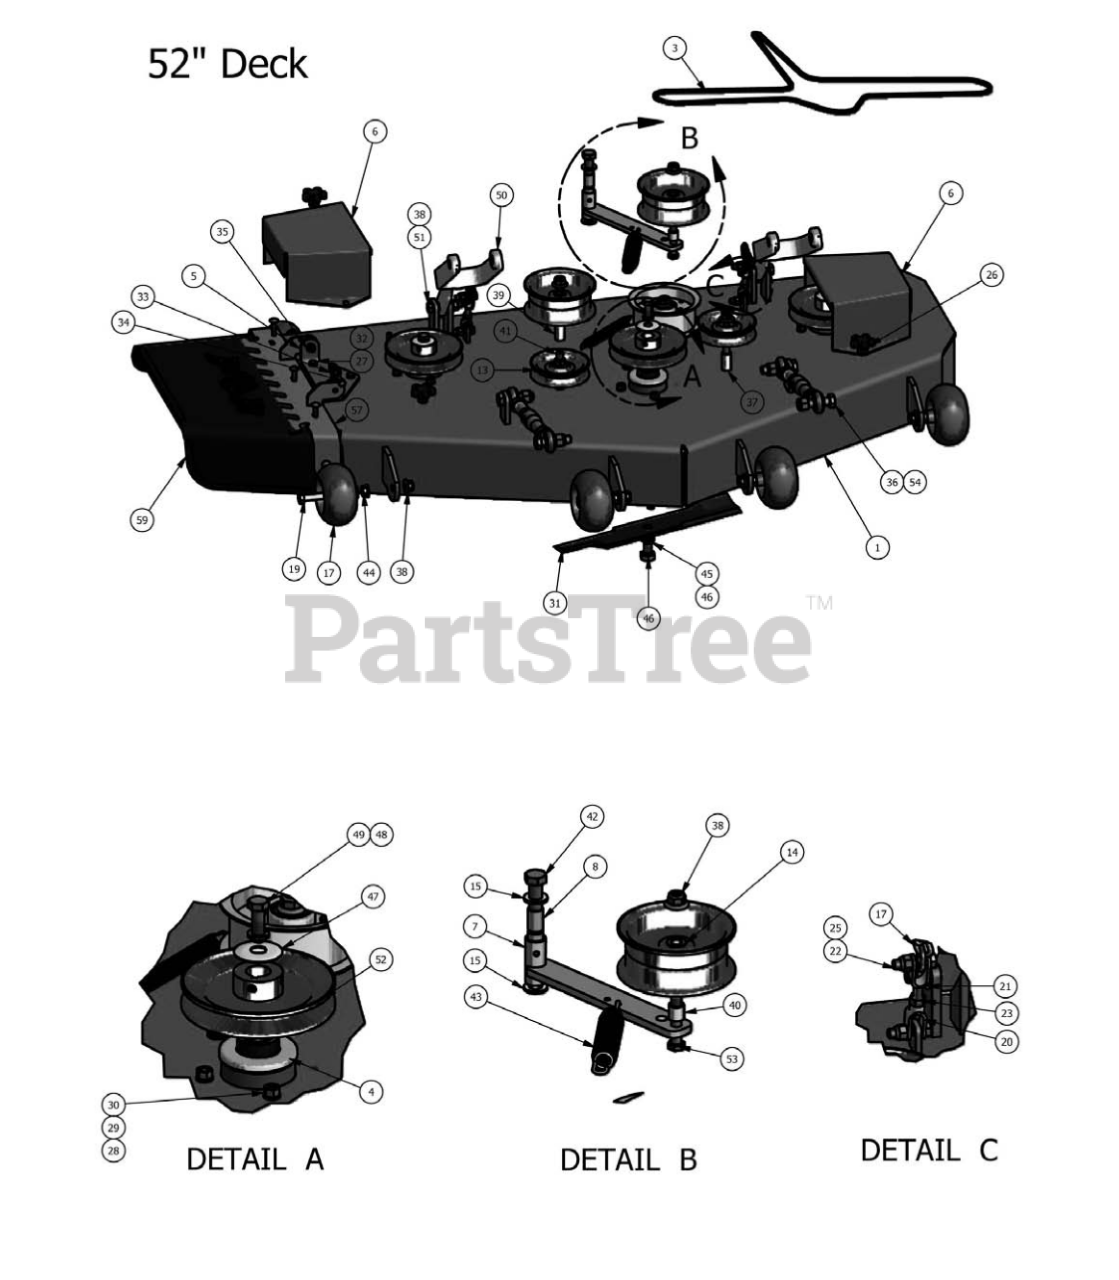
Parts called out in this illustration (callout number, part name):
1	52" Deck Shell
2	52" Deck Assembly
3	52" Deck Belt
4	Double Bearing Spindle (Complete)
5	Discharge Chute Hanger
6	Pulley Cover
7	Deck Idler
8	5/8" ID x 1 1/8" Brass Bushing
9	1/2" x 3" Hex Bolt
10	1" Collar Spacer
11	1/2-13 Nylon Flange Nut-Orange
12	deck Idler Spring
13	43/4" Idler Pulley
14	5 3/4" Deck Idler Pulley
15	.635 ID Plastic Washer
16	Turnbuckle (Top Link)
17	Anti-Scalp Rollers
18	Deck Wheel Assembly
19	1/2" x 4" Bolt (Grade 8)
20	Female Yoke
22	3/8" x 1 1/2" Hex Bolt
23	3/8" Hex Nut
24	3" Chain Assembly
25	3/8 Nylock Nut
26	5/16" Knob
27	3/8" x 3/4" Hex Bolt
28	3/8 x 1 1/4 Bolt
29	3/8" Lock Washer
30	3/8" Hex Nut
31	52" Fusion Blade
32	3/8" Flange Nut
33	.360 ID Plastic Washer
34	5/16" x 1" Hex Bolt
35	5/8 Nylock Nut
36	5/8" x 2 1/2" Hex Bolt
37	Pup Pulley Spacer
38	1/2-13 Nylon Flange Nut-Orange
39	13/4" Pulley Spacer
40	3/4 OD x 1/2 ID x 3/4 Length
41	1/2 x 3 1/2 Flange Bolt
42	5/8" x 4" Hex Bolt
43	Deck Idler Spring
44	1/2" Flange Nut
45	5/8" Lock Washer
46	5/8 x 1 1/2" Grade 8 Bolt
47	Cup Washer
48	1/2" Lock Washer
49	1/2" x 1 1/2" Fine Thread Bolt
50	Deck Arm Assembly
51	1/2" x 2 1/2" Hex Bolt
52	5" Deck Pulley
53	1/2 x 3" Bolt
54	5/8 Std NC Nylock Nut
55	52" Lower Hanger
56	5/16" Nylock Flange Nut
57	52" Discharge Chute Upper Hanger Plate
58	5/16" x 1 1/4" Carriage Bolt
59	Rubber Discharge Chute Assembly
60	Discharge Chute (Rubber Only)
